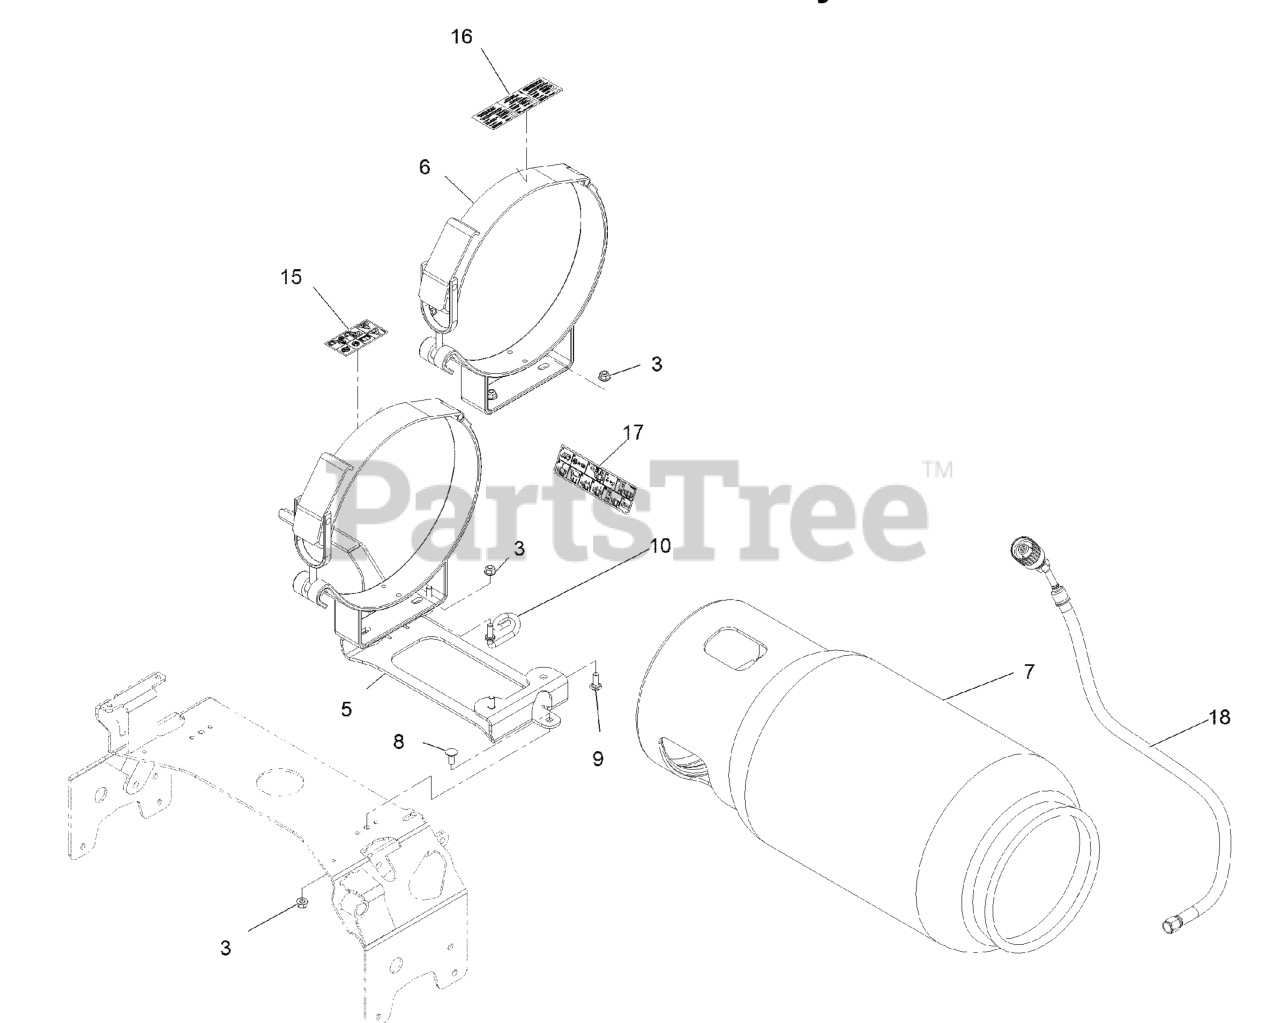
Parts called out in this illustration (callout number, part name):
3	NUT-HF, NI
5	WELD, TANK MOUNT
6	BRACKETS, LPG TANK - HORI
7	TANK, LP - 33.5 LB.HORIZO
8	SCREW-CARR
9	SCREW-CARR
10	RETAINER, LP HOSE
15	Decal-LPG Warning
16	Decal-LPG Horiz Tank Spec
17	Decal-LPG Fuel Tank Replacement
18	ASM, LPG HOSE W/CONNECTOR
